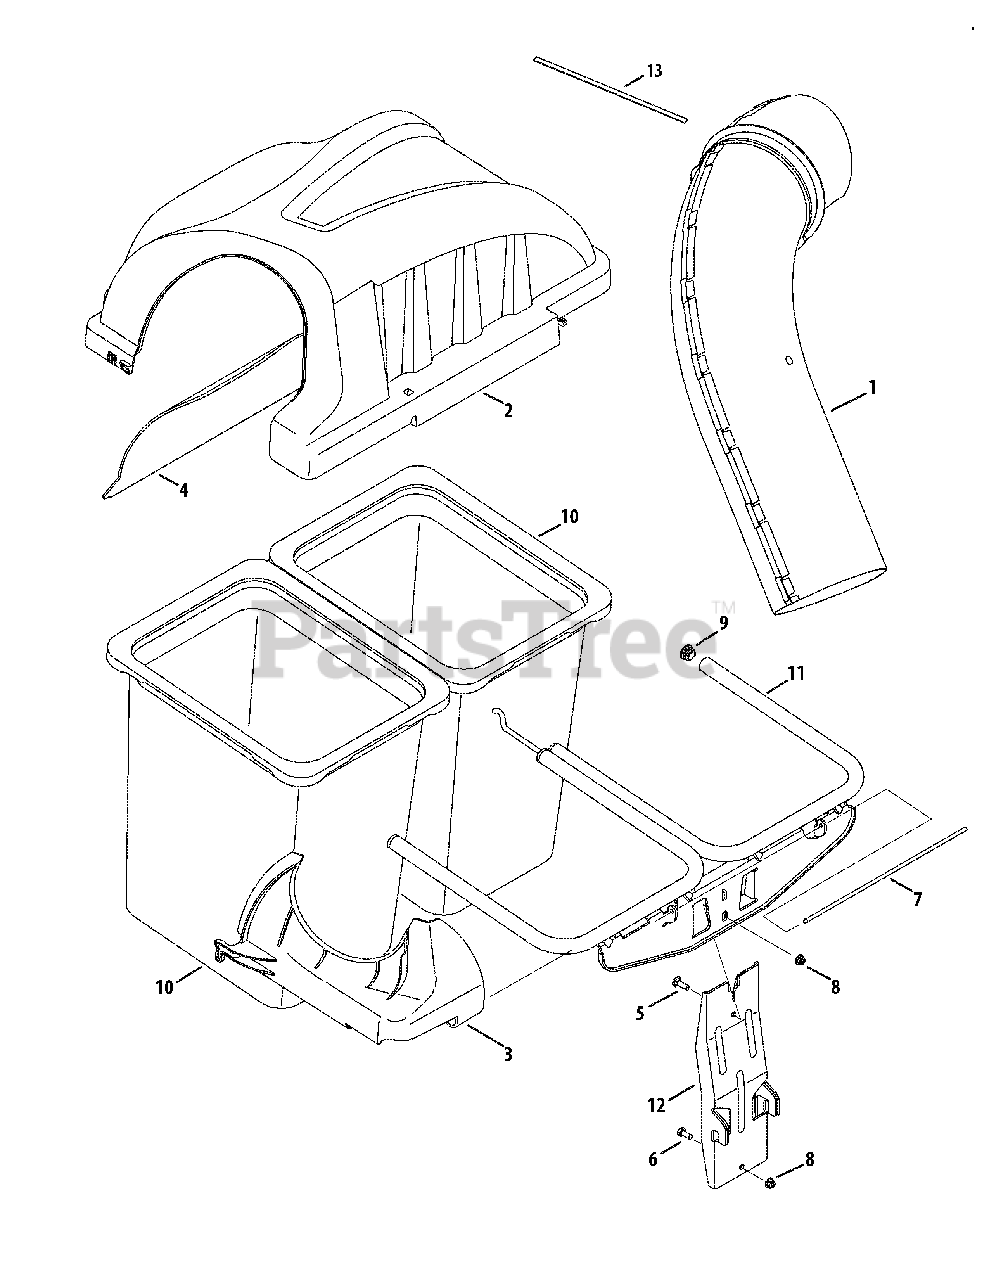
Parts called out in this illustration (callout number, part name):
1	Upper Chute Assembly
2	Twin Bagger Cover Assembly
3	Upper Chute Support
4	Bagger Cover Screen
5	Carriage Screw, 5/16-18 x 1.00"
6	Hex Head Screw, 5/16-18 x .75"
7	Cover Hinge Pin
8	Flange Lock Nut, 5/16-18
10	Grass-bag Assembly
13	Adhesive Strip
